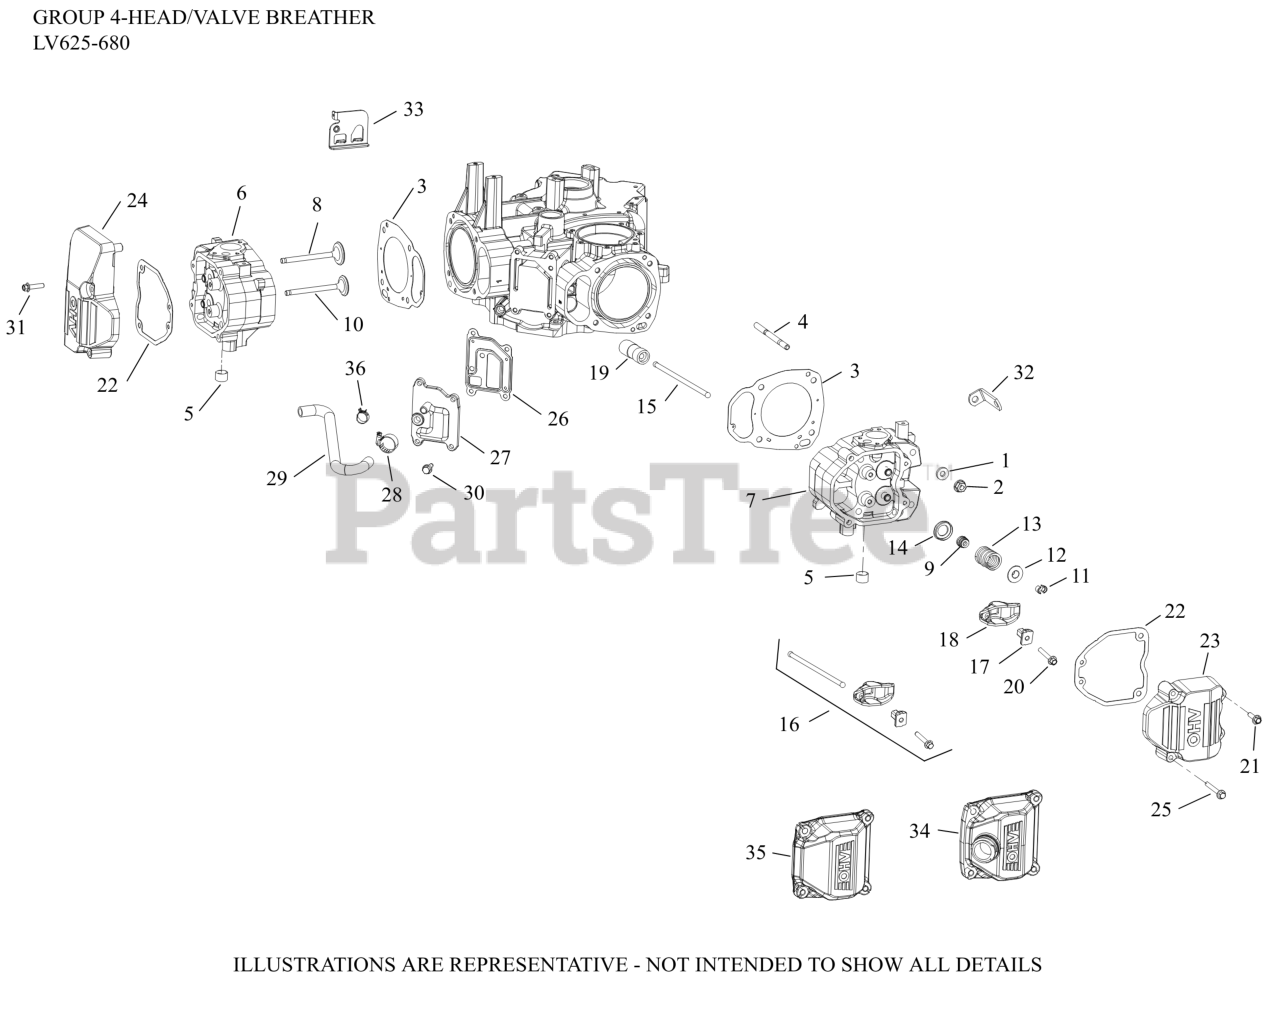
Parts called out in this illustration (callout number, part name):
1	WASHER, FLAT 5/16"
2	NUT, FLG M8X1.25
3	GASKET, CYLINDER HEAD-USE 66 841 02-S
5	PLUG, PIPE
6	KIT,CYLINDER HEAD #1
7	KIT,CYLINDER HEAD #2-(#DSC)
8	VALVE, INTAKE (STD)
8	VALVE, INTAKE (.25)
9	SEAL, VALVE STEM-USE 25 032 14-S
10	VALVE, EXHAUST (STD)-USE 32 016 01-S
10	VALVE, EXHAUST (.25)
11	KIT, RETAINER
12	RETAINER, VALVE SPRING - USE 25 173 28-S
13	SPRING, VALVE
14	RETAINER-USE 235011-S
15	ROD, PUSH
16	KIT, VALVE TRAIN
17	PIVOT, ROCKER ARM
18	ARM, ROCKER
19	LIFTER, HYDRAULIC VALVE-USE 25 351 10-S
20	SCREW, ROCKER ARM PIVOT-USE M-640034-S
21	SCREW, FLG M6X1.0X25
22	GASKET, VALVE COVER
23	KIT, ROCKER COVER
24	KIT, RCKR CVR W/BREATHER-DISC.
25	SCREW, FLG M6X1.0X50
26	GASKET USE 24 041 51-S
26	GASKET, BREATHER-USE 24 041 67-S
27	COVER, BREATHER -USE 24 096 125-S
29	HOSE, BREATHER-DISCONTINUED
30	SCREW,FLG THD FRM M6X1.0X20-(#25086396S)
